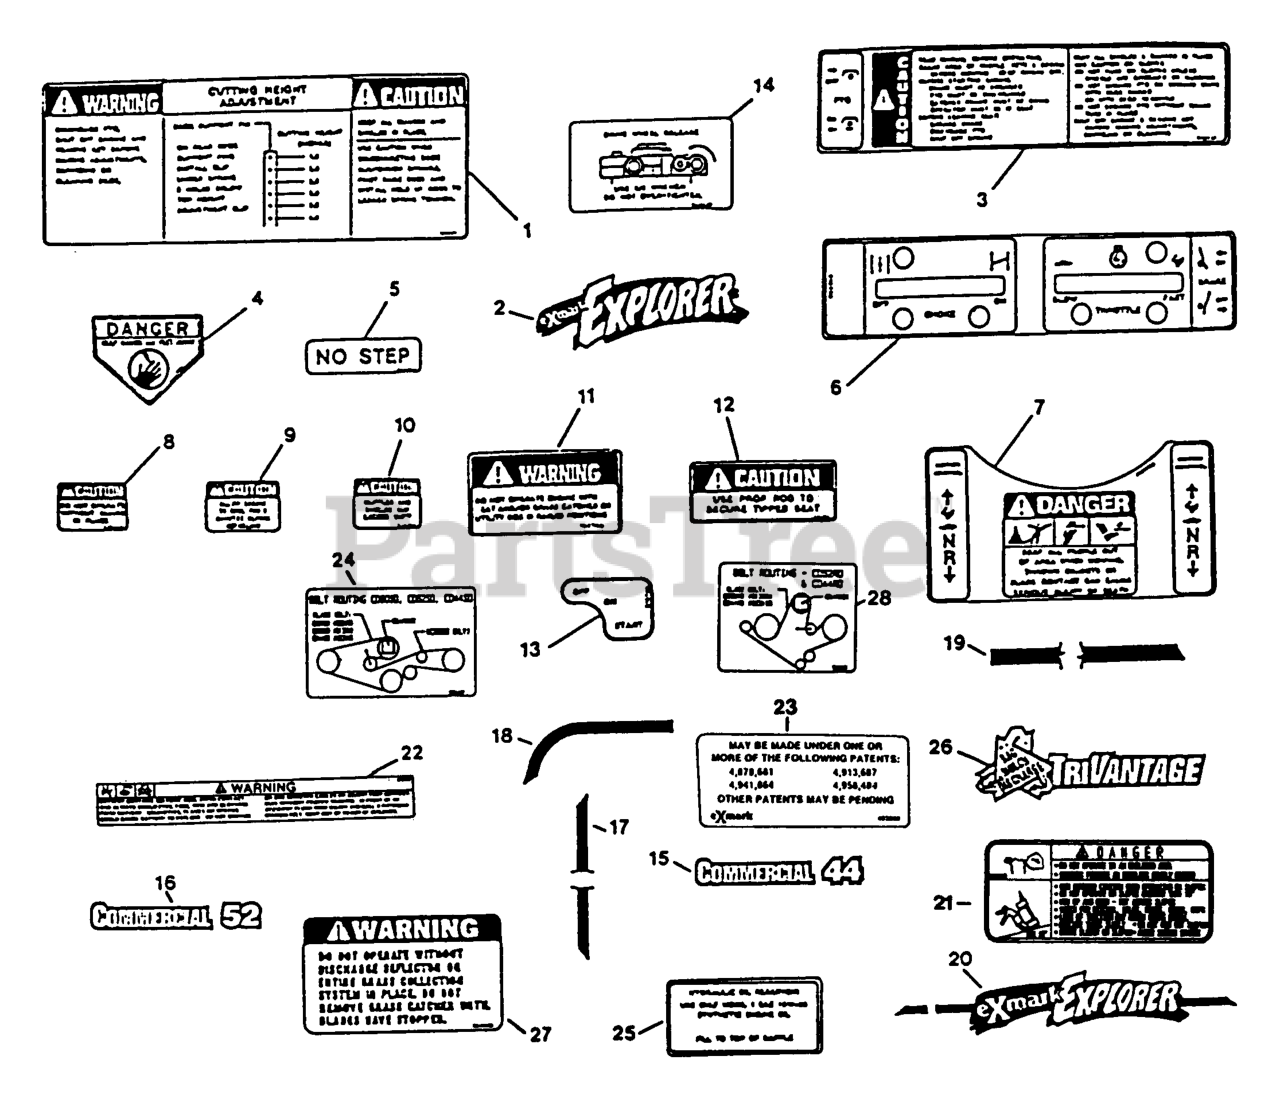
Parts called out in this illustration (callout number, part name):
2	DECAL,EXMARK EXPLORE
3	DECAL,FENDER RH
4	DECAL-DANGER
5	DECAL,NO STEP
7	DECAL,CONSOLE
8	DECAL-GUARD
15	DECAL,COMMERCIAL 44
16	DECAL,COMMERCIAL 52
17	DECAL,CATCHER FRONT
18	DECAL,LH CATCHER STR
21	DECAL,DANGER
22	DECAL-BATTERY
24	DECAL,BELT RTNG CD52SD
25	DECAL,HYD TANK
27	DECAL-WARNING, DISCHARGE
28	DECAL,BELT RTNG CD52RD
